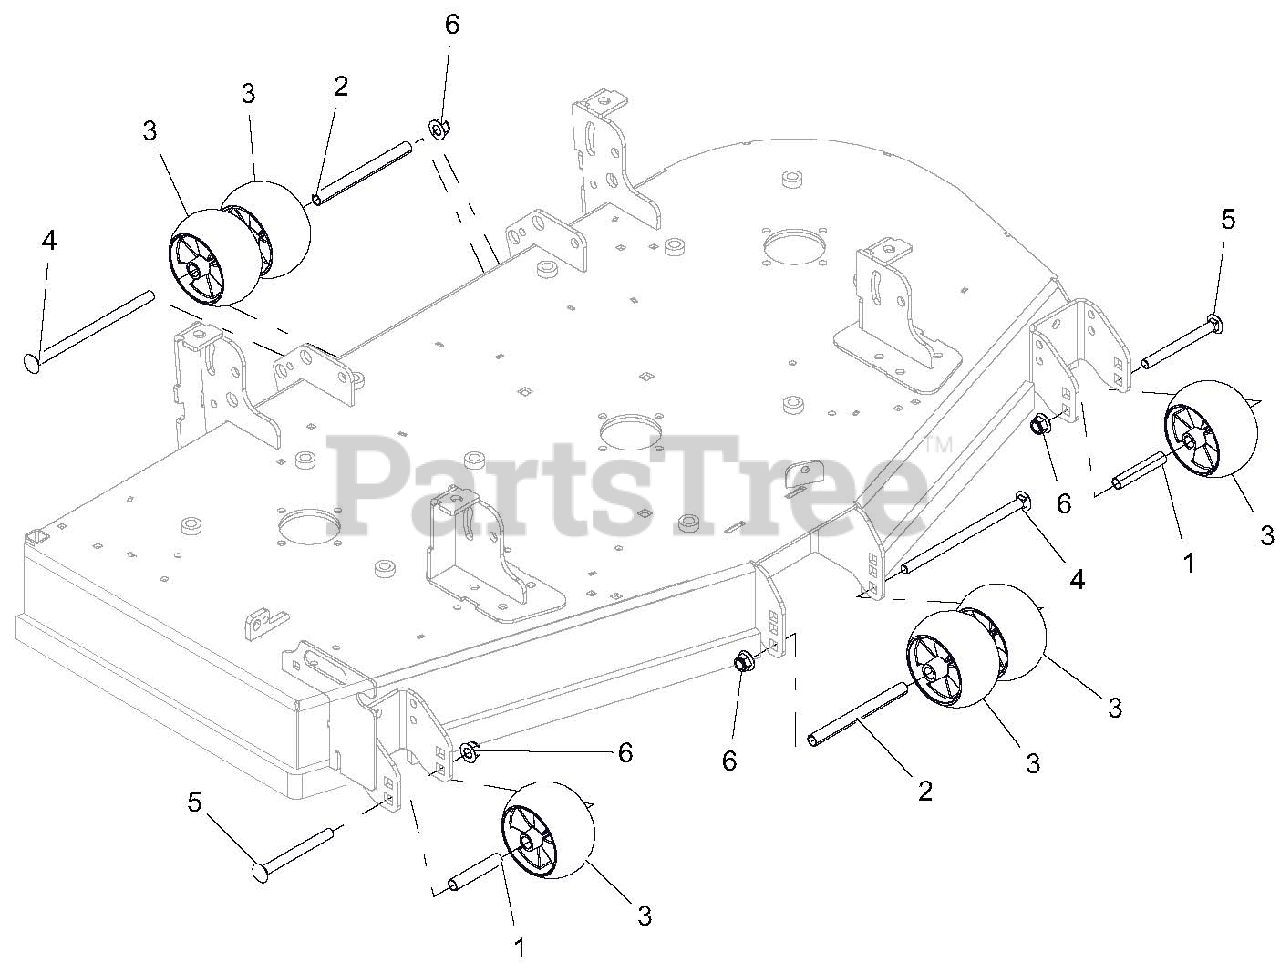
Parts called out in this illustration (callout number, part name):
1	SPACER, .510X.625X3.35
2	SPACER, .510X.625X6.70
3	ANTI-SCALP WHEEL - 5X3 CTR
4	BLT-RDHDSQNK .50-13X8.50 Y
5	BLT-RDHDSQNK .50-13X5.00 G5 YWZC
6	NUT-LK-NYL-FLG .50-13 YWZC
